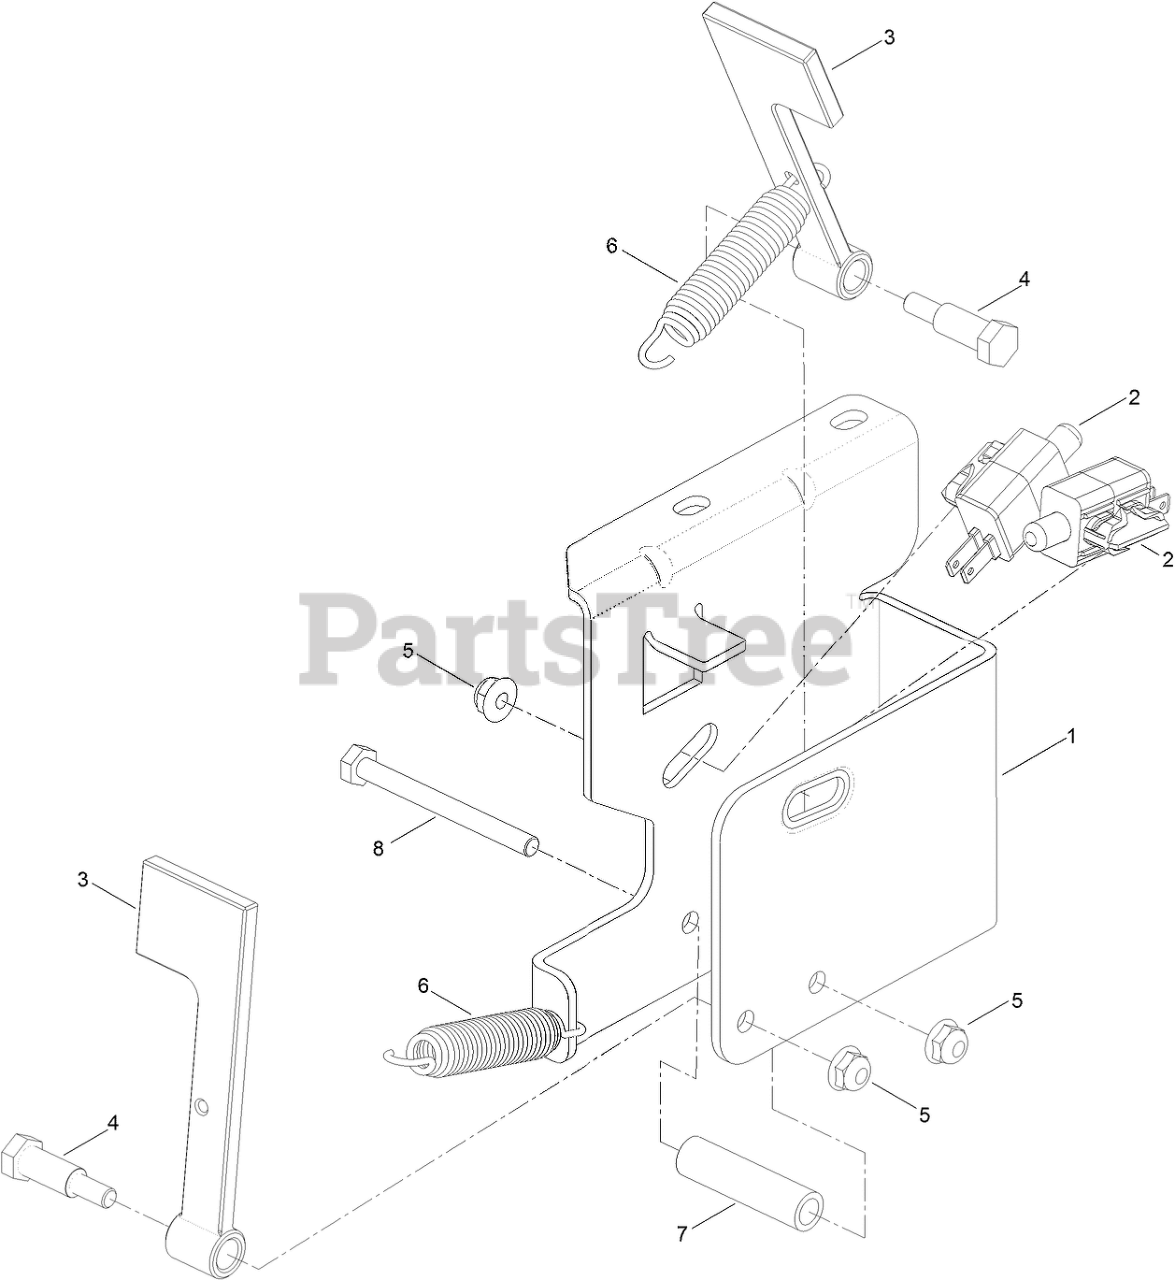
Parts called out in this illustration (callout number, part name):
1	BRACKET-SWITCH
2	SWITCH
3	ARM-SWITCH
4	BOLT-SHOULDER
5	NUT-HF
6	SPRING-EXTENSION
7	SPACER
8	SCREW-HH
